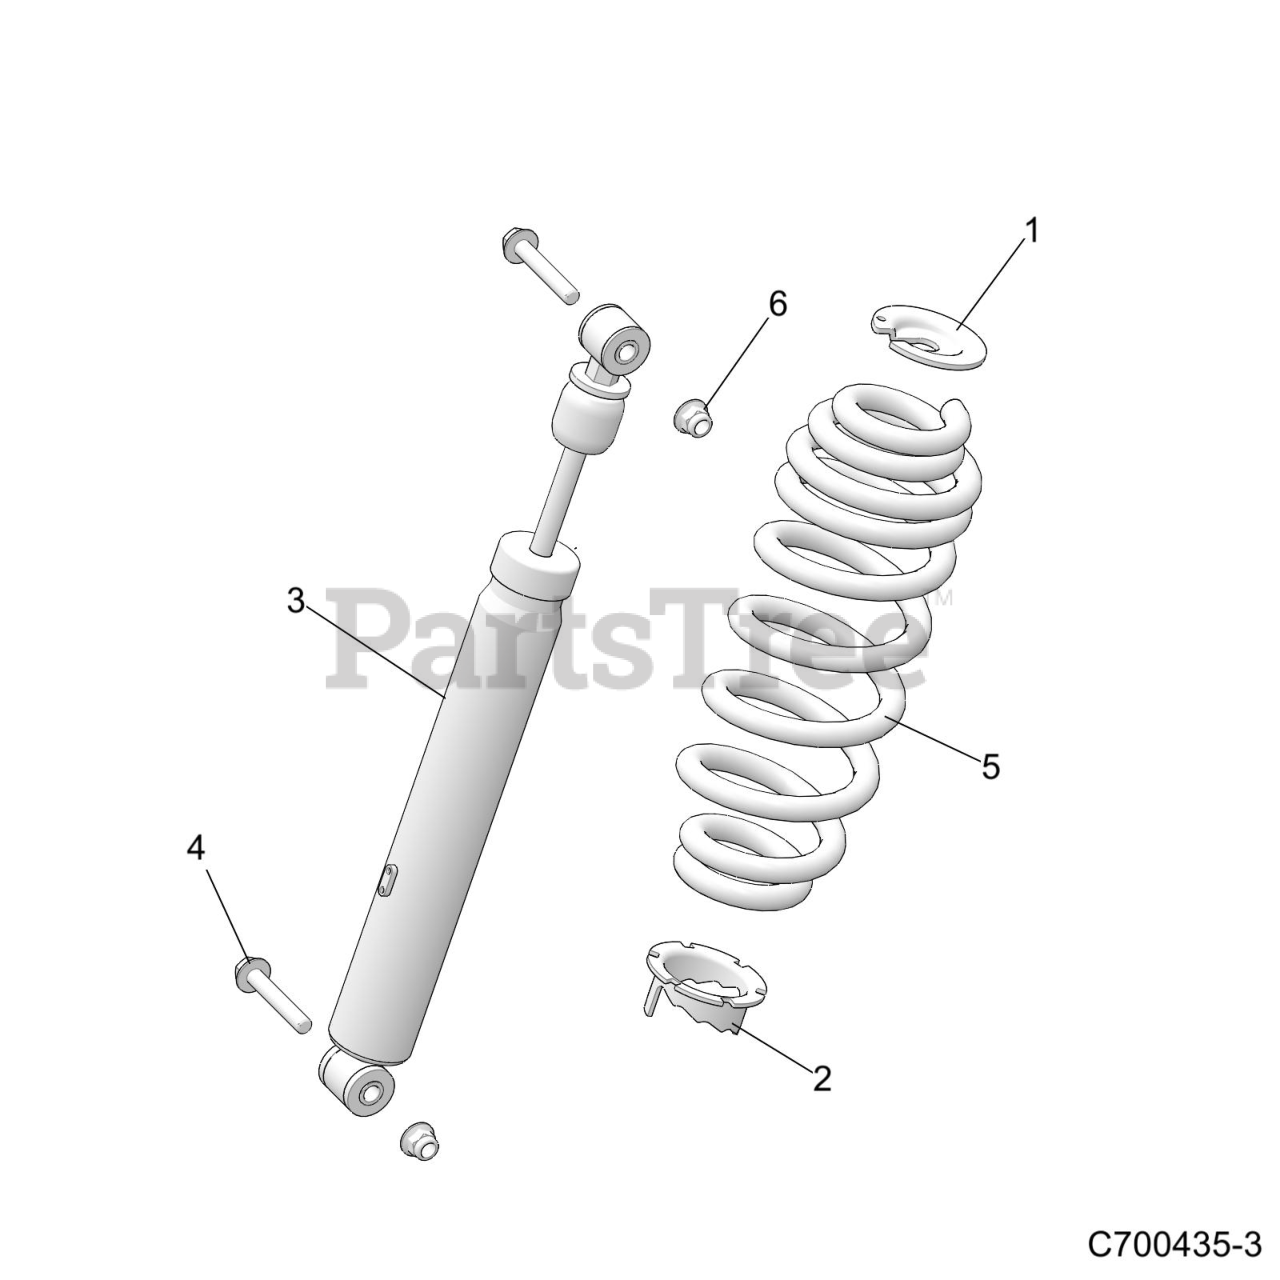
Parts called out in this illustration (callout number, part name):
1	RETAINER-SPRING,STEEL
2	CAM-ADJUSTER,ALUMN,2.30
3	SHOCK-REAR
4	SCR-HXFL-M10X1.25X60 10.9 ZOD
5	SPR-360-500#,14.6FL,2.3ID,BLK
6	NUT-M10X1.25,FLG,NYLOC-OLIVE D
